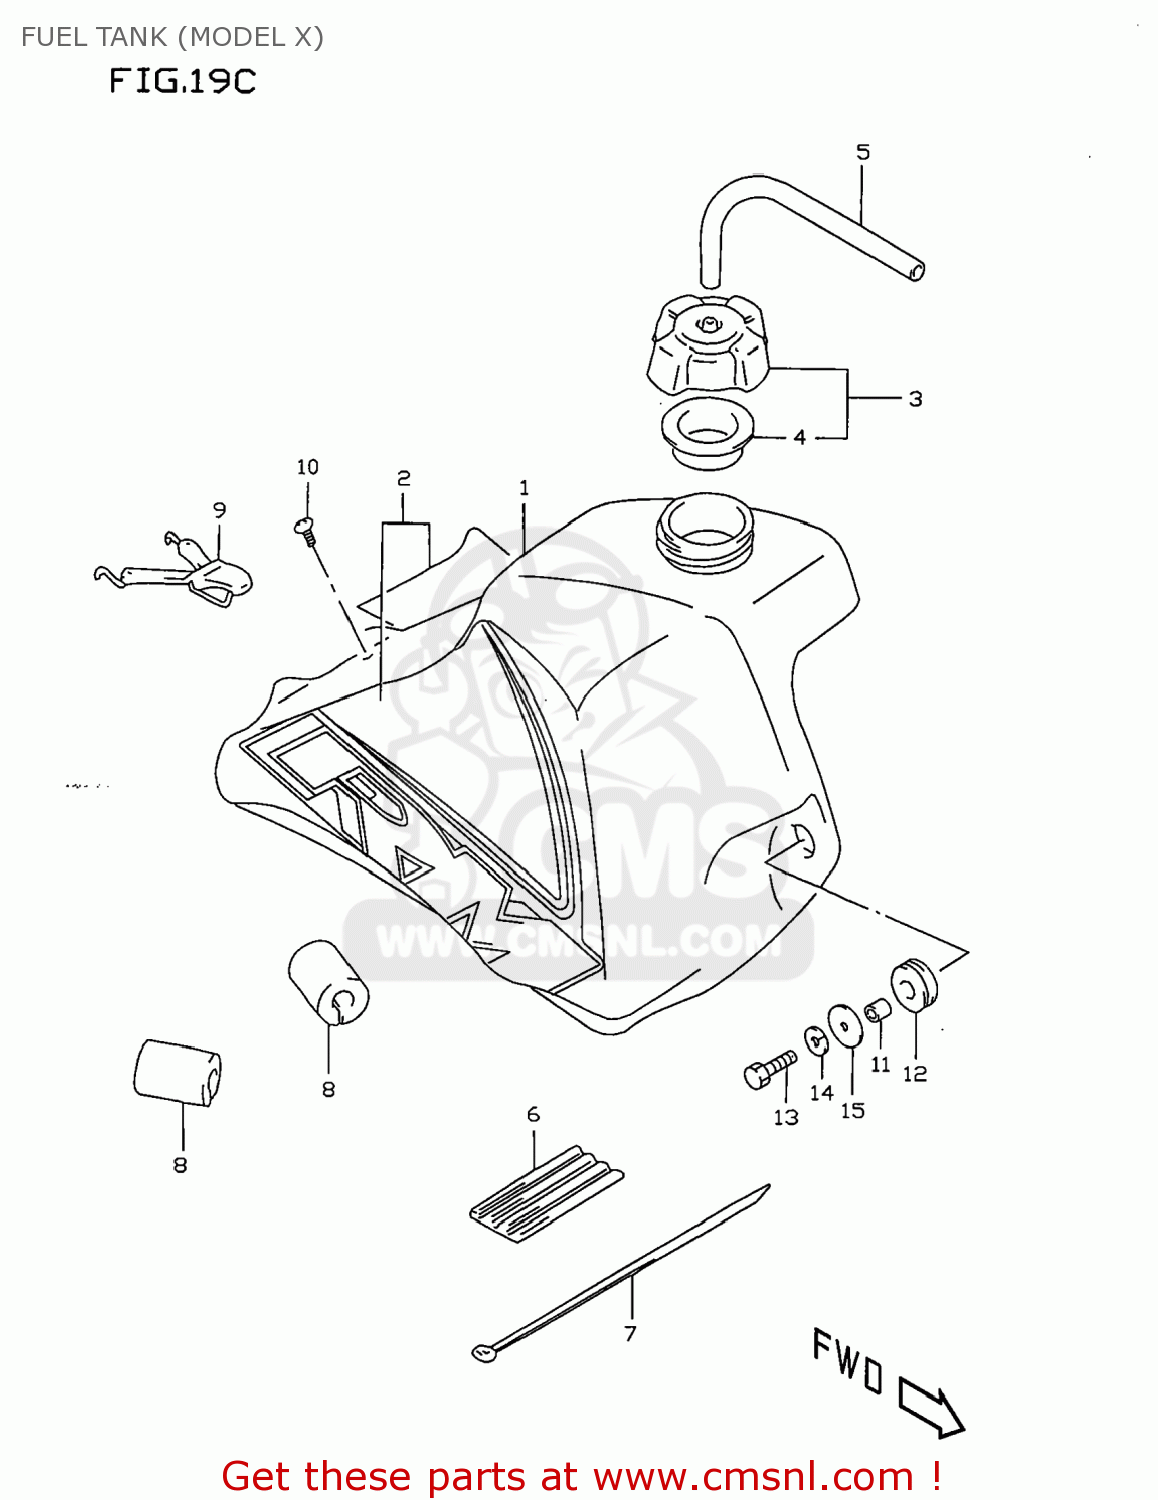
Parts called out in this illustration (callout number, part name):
1	TANK,FUEL(YELLOW)
2	TAPE SET,FUEL TANK
3	CAP SET,FUEL TANK
4	GASKET,CAP (NAS)
5	HOSE(5X8.2X600)
6	CUSHION,FUEL TANK UPR FR
7	CLAMP(L:250)
8	CUSHION,FUEL TANK UPR RR
9	BAND,FUEL TANK RR
10	SCREW
11	SPACER(6.5X10X11.5)
12	CUSHION
13	BOLT
14	LOCK WASHER
15	WASHER(6.5X24X1.6)
